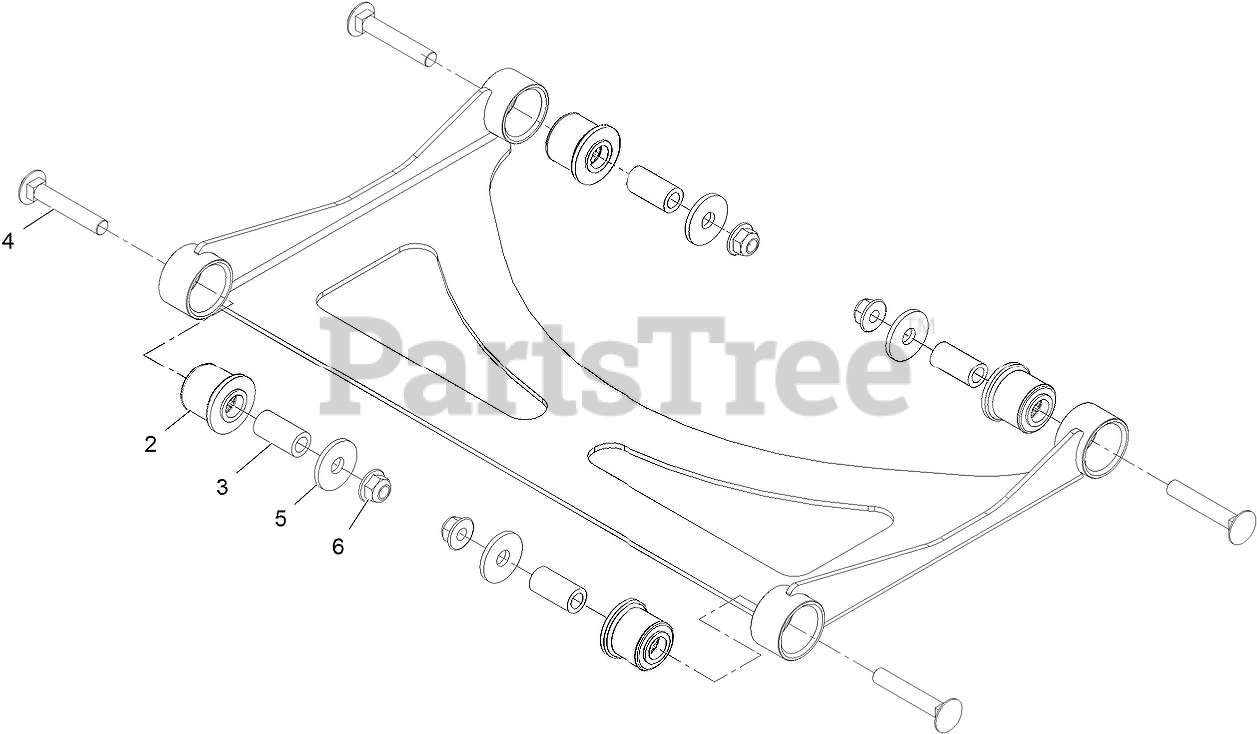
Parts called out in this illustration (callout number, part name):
2	BUSHING-RUBBER, SUSPENSION
4	Bolt-Carriage 3/8-16 X 2 1/4
5	WASHER
6	NUT-HF, NI
